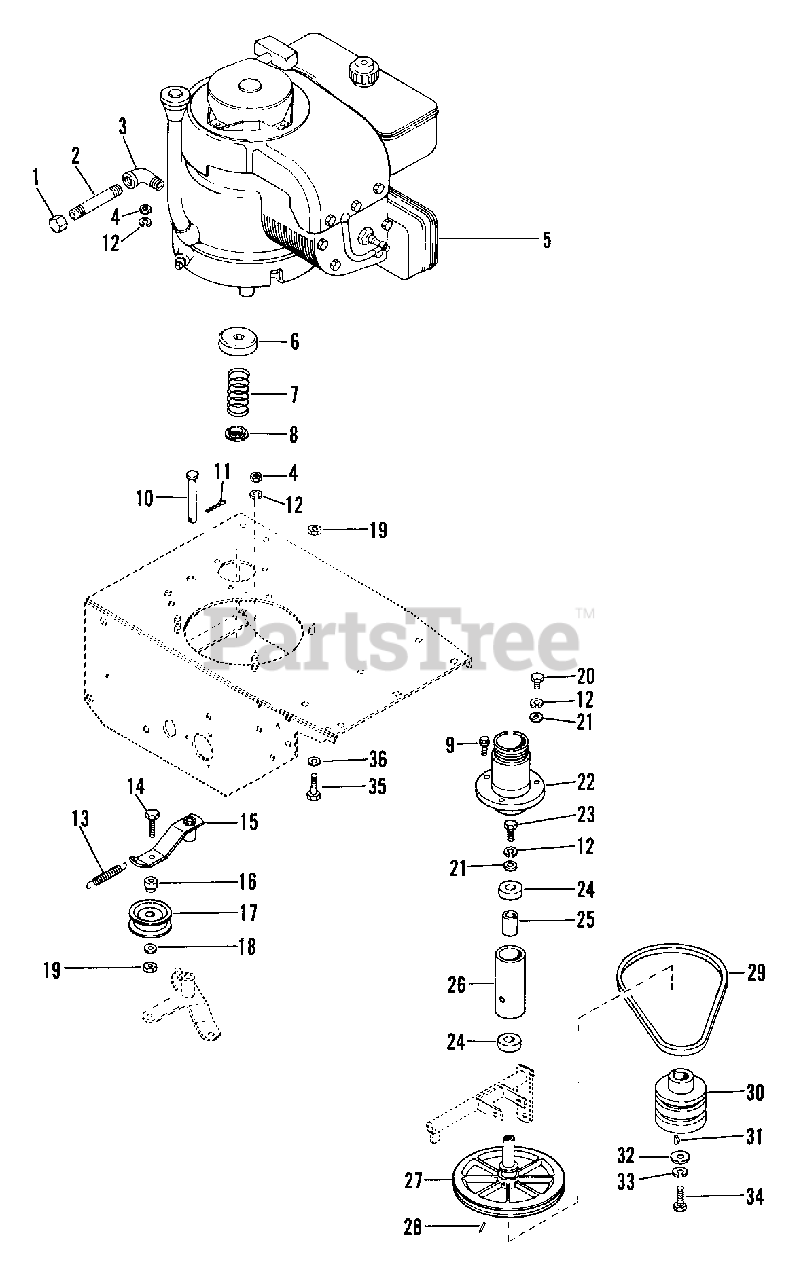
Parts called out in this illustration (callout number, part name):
1	HEX CAP
1	HEX PIPE CAP
2	NIPPLE
3	90 STREET ELBOW
4	NUT-HEX .312-18
5	6HP TEC RECOIL
5	6HP TEC. ELEC
5	6 HP RECOIL TEC GROUND TO RUN
5	6 HP ELEC TEC GROUND TO RUN
5	8 HP ELEC TEC GROUND TO RUN
7	SG-COMP .148X1.23X2.53 WLD87
8	SPRING RETAINER
9	BLT-SERHFWH .31-18X.50 PL
10	PIN-CLEVIS .500 X 3.250
11	PIN-COTR .12X1.0 PL
12	WSHR-LK .312X.097 PL HVY
13	SG-TENS .063X.44X2.81 WLD 18
14	BLT-HEX .31-18X1.25 PL GR2
15	IDLER ARM
16	SPCR, BRG .315X.50X.688X.281
17	IDLER
18	WSHR-FL-STL .38X.875X.083 PL
19	NUT-LK .312-18 GR A PL
20	BLT-HEX .31-18X.50 PL GR2
21	WSHR-FL-STL.312X.734X.065PL
22	DRIVE SPRING HOUSING
23	BLT-LK .31-18X.75 GR 5
24	BRG-BALL .625X1.375X.44
25	BEARING SPACER .87 X .63 X 1.2
26	DRIVE SPINDLE HOUSING
27	DRIVE DISK
28	PIN-ROLL .188X1.25
29	V-BELT, SAE 380-RAW EDGE
30	ENGINE SHEAVE
31	KEY-WDRF .156X.625X.25 SAE 6
31	KEY-SQ .25 X 1.50 X .25 SAE
32	WSHR-FL-STL .438X1.125X.19
33	WSHR-LK .375X.115 HVY PL
34	BLT-HEX .38-24X1.25 BLKO GR5
35	BLT-HEX .31-18X1.25 PL GR5
36	WSHR-FL-STL.344X.688X.065PL
